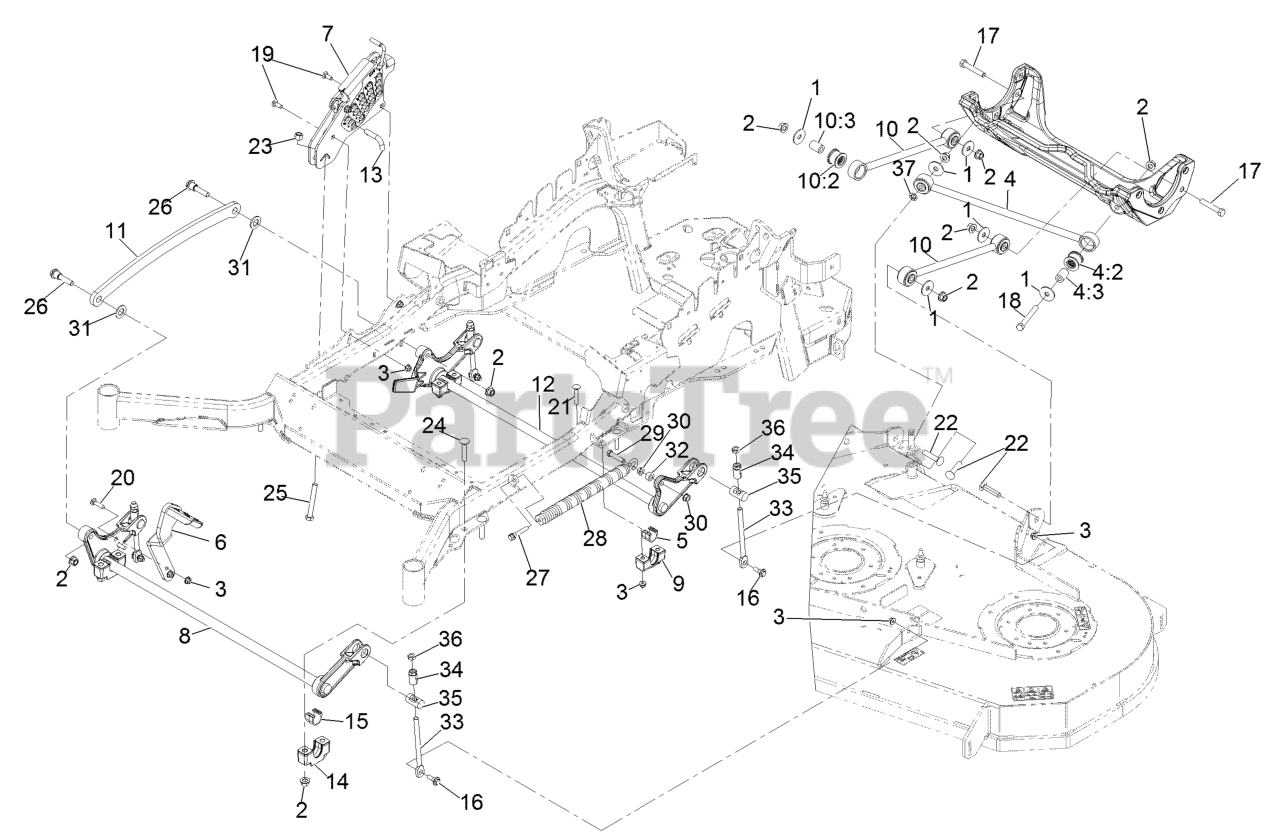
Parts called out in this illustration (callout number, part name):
2	Nut-Lock 1/2-13
3	Nut-Nyloc 3/8-16 Flg
4	Panhard Rod ASM
4:2	Bushing-Suspension, Rubber
5	Bearing-Cross Shaft, Rear
6	Lever-Foot
7	HOC ASM
8	Decklift-Front
9	Support-Cross Shaft, Bearing Rear
10	Deck Strut ASM
10:2	Bushing-Suspension, Rubber
11	Link-Lift, Deck
12	Lift-Deck, Rear
13	Pin-HOC
14	Support Cross Shaft, Bearing
15	Bearing-Cross Shaft, Front
16	Screw-Hex Flange 3/8-16 X .80
17	Screw-HH 1/2-13 X 3
18	Screw-HH 1/2-13 X 4
19	Bolt-Carriage 3/8-16 X 1
20	Bolt-Carriage 3/8-16 X 1 1/2
21	Bolt-Carriage 3/8-16 X 2 1/4
22	Bolt-Carriage 1/2-13 X 2 1/2
23	Nut-Nyloc 1/2-13
24	Bolt-Carriage 1/2-13 X 2 1/2 Spl Neck
25	Bolt-HH 1/2-13 X 4 Tap
26	Screw-Hex Flange 1/2-13 X 1.90
27	Screw-Shcs 3/8-16 X 2.212
28	Spring-Extension
29	Screw-HH 7/16-14 X 2
30	Nut-Whizlock 7/16-14
31	Washer-3/4 SAE
33	Link-Adjuster, Deck Lift
34	Adjuster-Lift, Deck
35	Trunnion
36	Nut-Jam 1/2-13
37	Nut-Push
